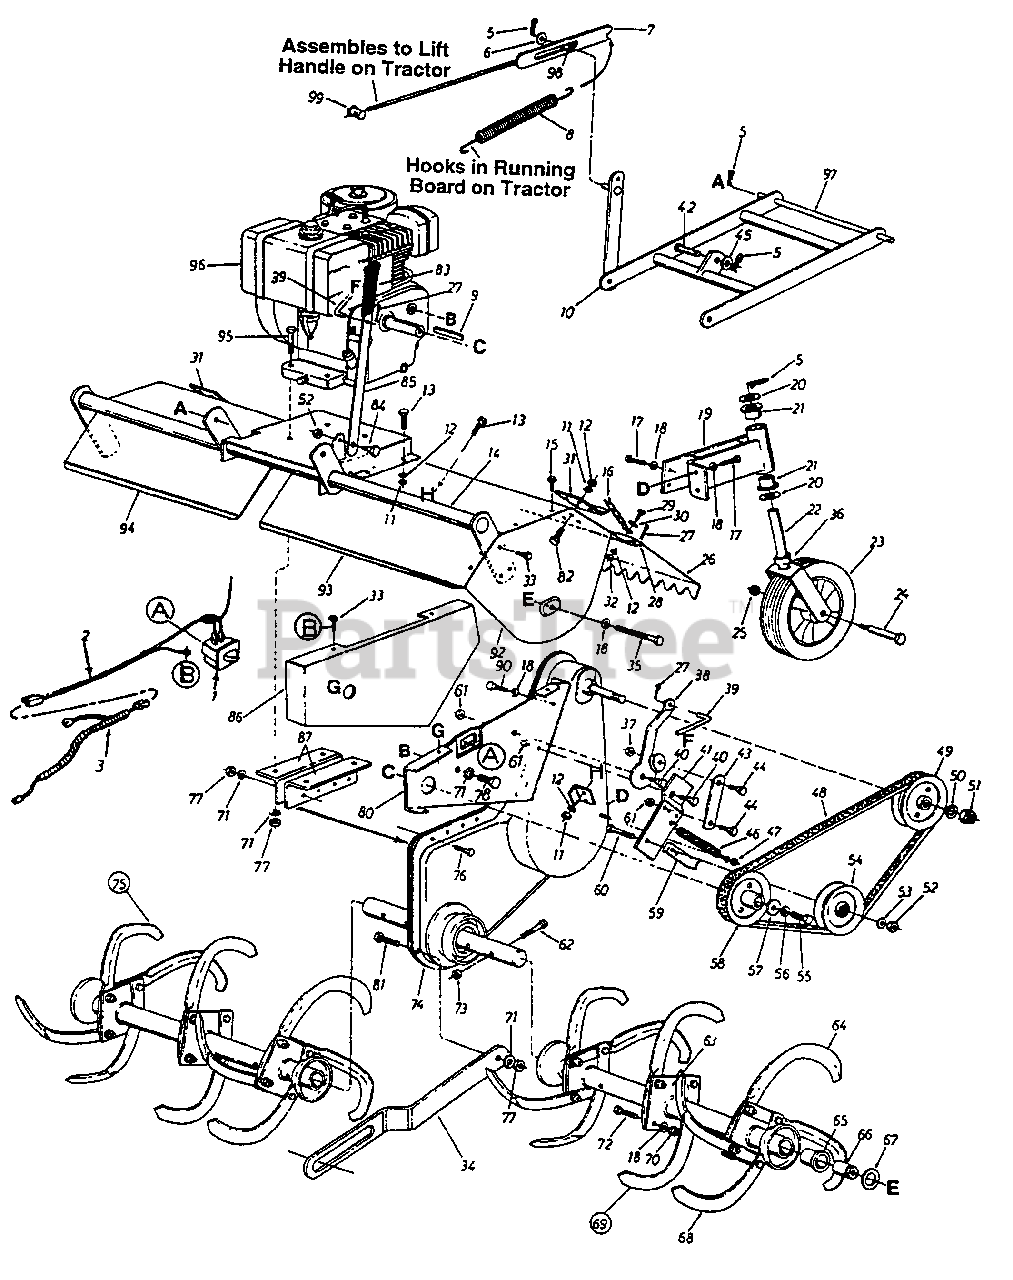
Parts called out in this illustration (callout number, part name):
2	Wire Harness
3	Adapter Harness
5	Internal Cotter Pin
6	Fl-Wash. 1/2" I.D. x .93" O.D.
9	Sq. Key 1/4" x 1/4" x 2.00" Lg.
12	L-Wash. 1/4" l.D.
13	Hex Bolt 1/4-28 x .62" Lg.
16	#2 Dog Chain x 20" Lg.
17	Hex Wash. Hd. Self-Tap Scr. 3/8-24 x .75" Lg.
18	L-Wash. 3/8" I.D.
21	Flange Bearing 3/4" I.D. x 1.00" I.D.
24	Shoulder Bolt .623" I.D. x 3.62" Lg.
25	Hex Cent. L-Nut 7/16-14 Thd.
28	L.H. Flap Rod
29	Hex Bolt 1/4-20 x .62" Lg.
30	Fl-Wash. 1/4" I.D.
33	Hex Wash. Hd. Self-Tap Scr. 1/4" x .62" Lg.
36	Spacer.752" l.D. x 1.25" O.D.
37	Hex Cent. L-Nut 5/16-18 Thd.
40	Shoulder Bolt 7/16" Dia. x 1.75"
45	Fl-Wash .50" I.D. x 1.0" O.D. x .06
46	Extension Spring .62" O.D. x 6.12" Lg.
47	Hex Crown Nut 3/8-24 Thd.
48	"V"-Belt (Kevlar)
49	1/2" "V"-Pulley 4.75" O.D. x.625" Bore
50	L-Wash. 5/8" I.D.
51	Hex Ins. L-Nut 5/18-16 Thd.
52	Hex Cent. L-Nut 3/8-16 Thd.
53	Fl-Wash. 3/8" I.D.
54	idler Pulley 4.0" O.D.
55	Hex Bolt 7/16-20 x 1" Lg.
56	L-Wash. 7/16" I.D.
57	Fl-Wash. 7/16" I.D. x 1.38"
58	1/2" "V"-Pulley .475" O.D. x 1.00" Bore
61	Hex Cent. L-Nut 5/16-18 Thd.
62	Hex Bolt 7/16-14 x 2.00" Lg.
66	Spacer
67	Thrust Wash. 1/2 I.D. x 1.55"
71	L-Wash. 5/16" l.D.
72	Hex Bolt 3/8-24 x 1.5" Lg.
73	Hex Cent. L-Nut 7/16-14 Thd.
77	Hex Nut 5/16-18 Thd.
78	Hex Bolt 5/16-24 x.62"
80	Clutch Support Bracket
81	Shld. Bolt .435" Dia. x .265" 5/16-18 Thd.
82	Hex Bolt 1/4-28 x .75 Lg.
83	Plastic Grip
84	Shoulder Bolt .498" Dia. x .212" Lg.
96	8 H.P. Engine
97	Hitch Rod
98	Push Bar Sleeve .503" I.D. x .624" O.D.
99	Ferrule
